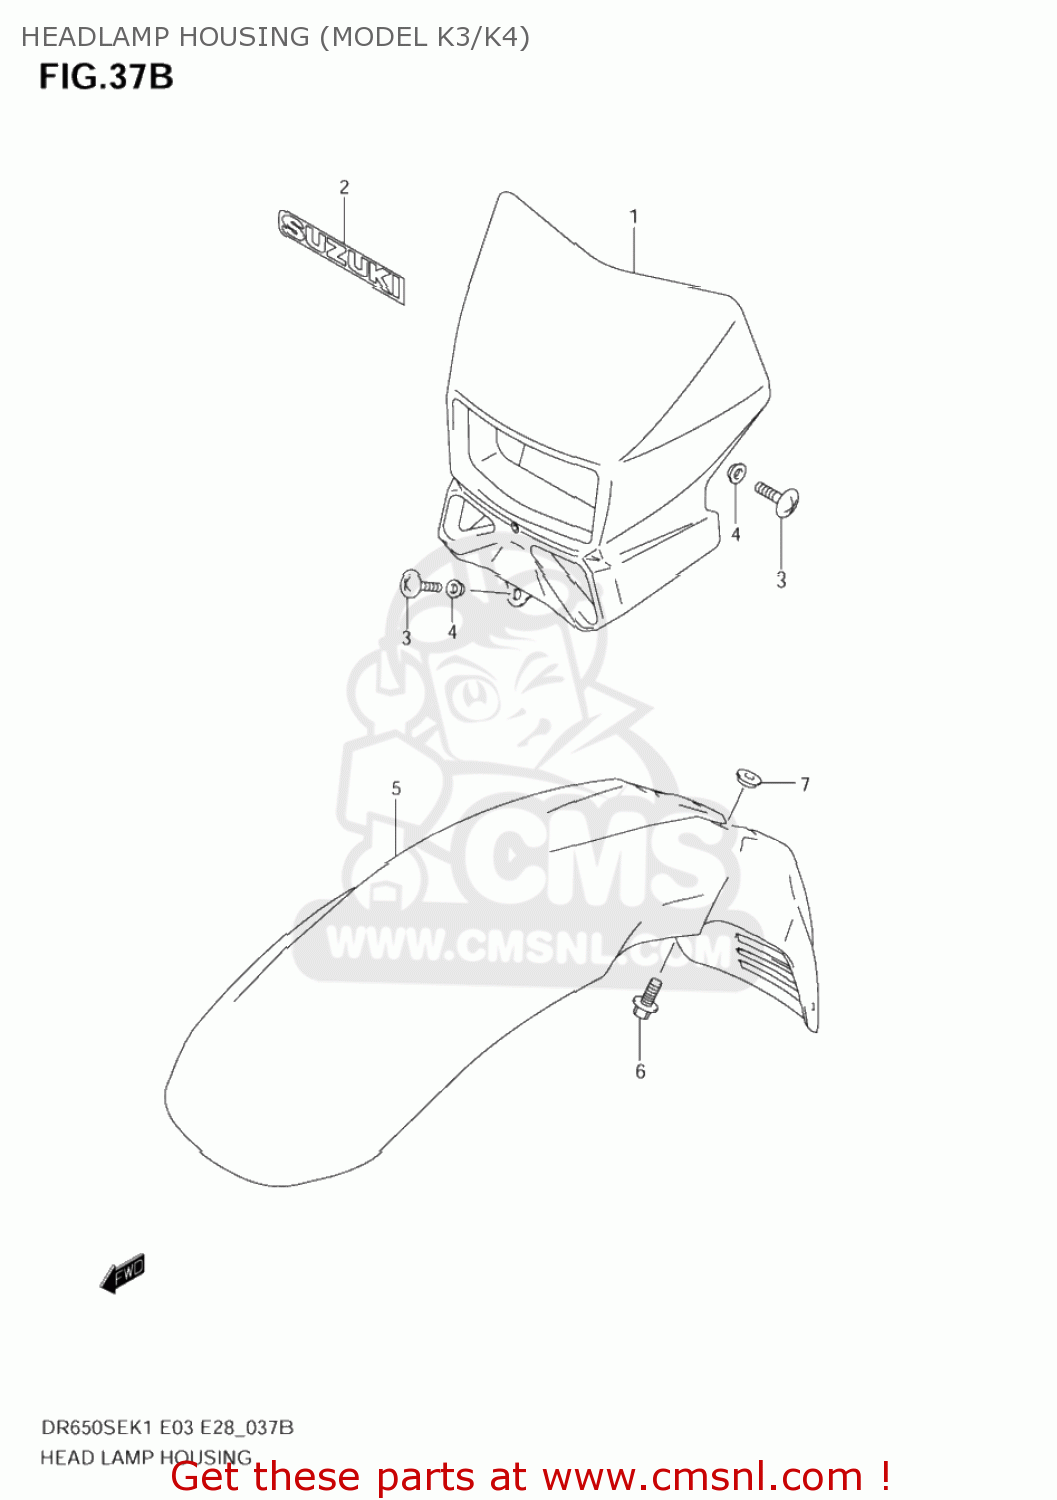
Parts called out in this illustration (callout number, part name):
1	COVER,HEADLAMP
2	EMBLEM,SUZUKI
3	SCREW 6X12
4	WASHER
5	FENDER,FR
6	BOLT(6X16)
7	WASHER
